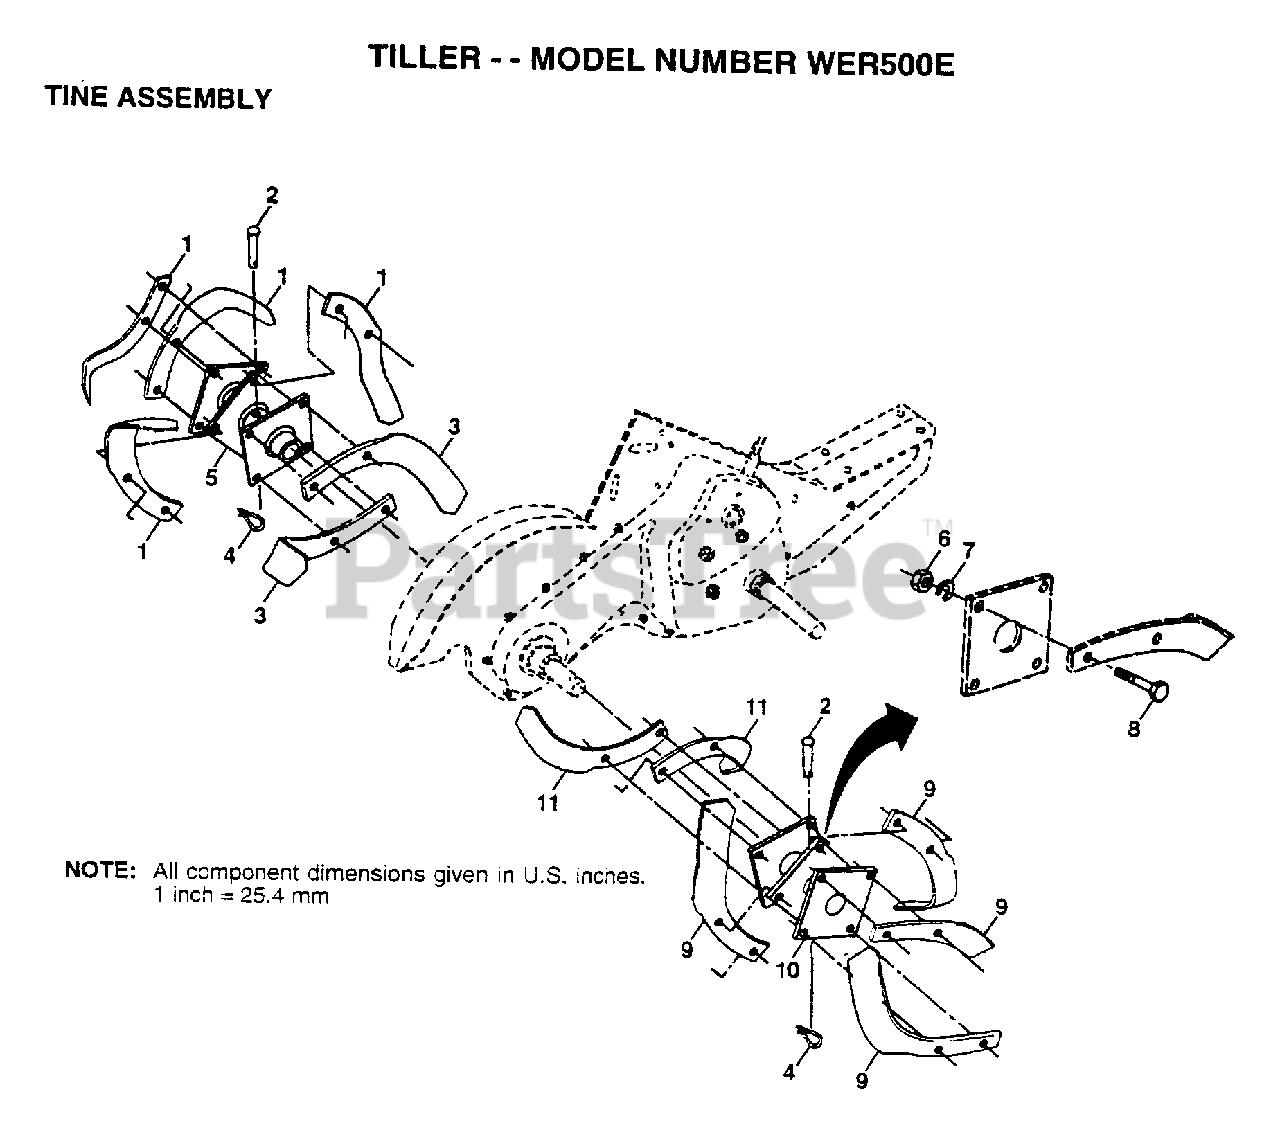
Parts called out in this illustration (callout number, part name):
2	PIN.CLEVIS.SHEAR
3	"TINE.LH.12"""
4	RETAINER.SPRING
5	HUB&PLATE ASM LH
7	LOCKWASHER
8	BOLT
10	HUB&PLATE ASM RH
11	"TINE.RH.12"""
